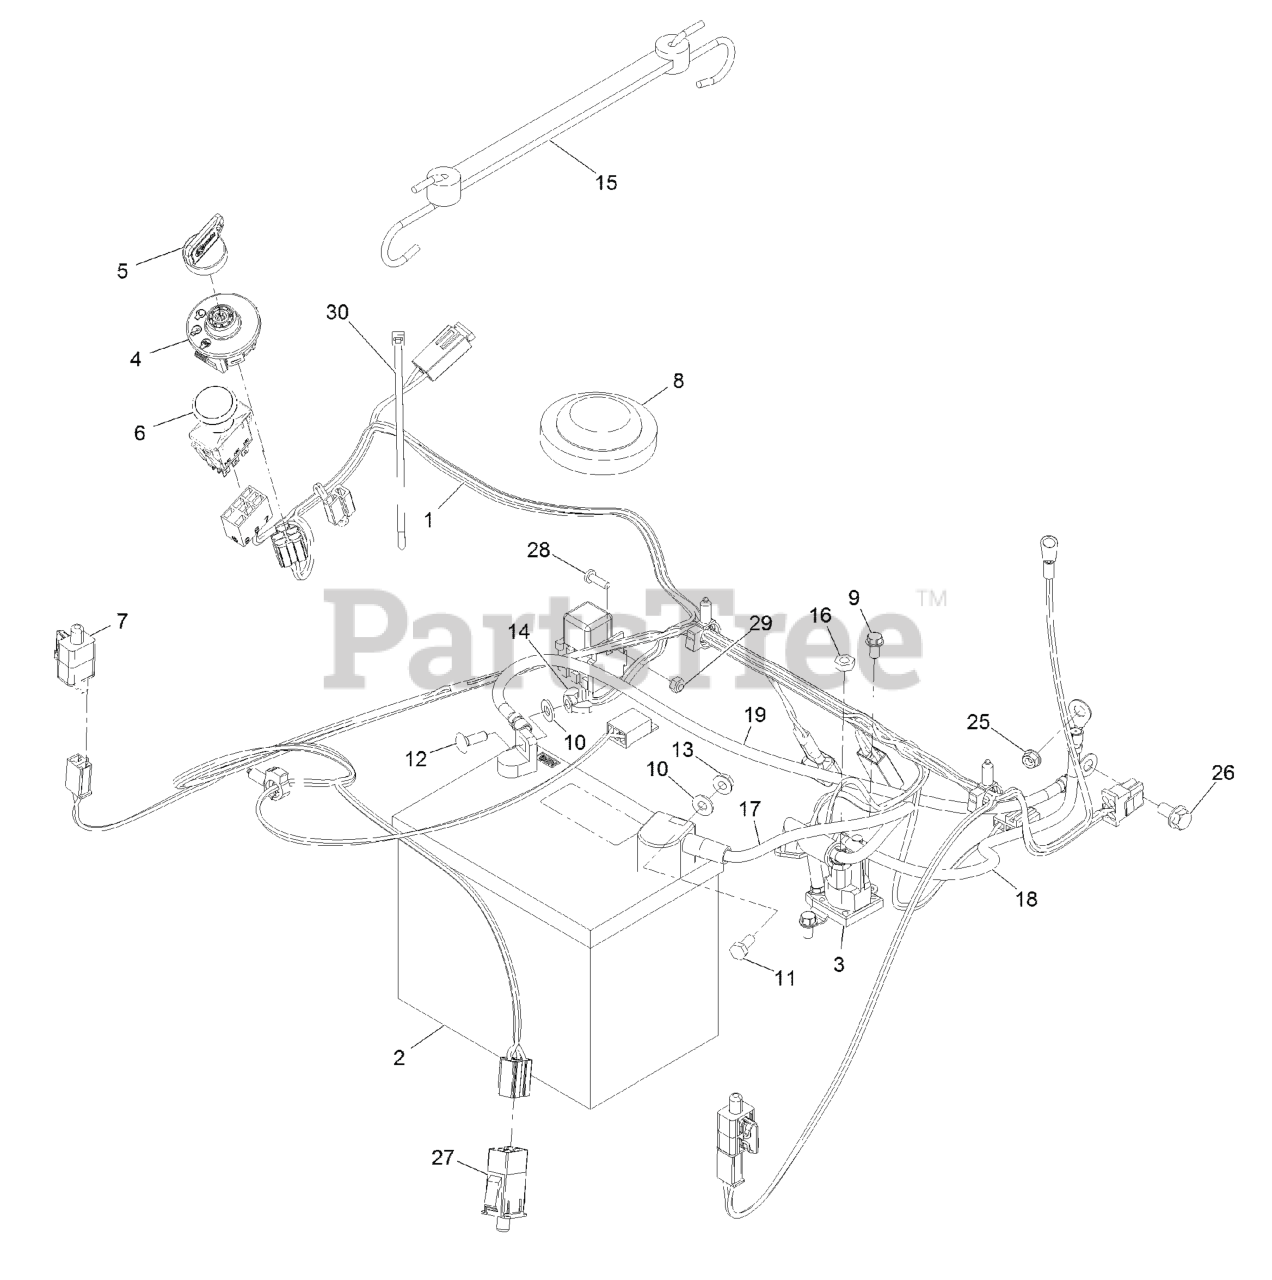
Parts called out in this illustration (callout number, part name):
1	HARNESS-WIRE
2	BATTERY
3	SOLENOID
4	SWITCH-IGNITION
5	KEY-IGNITION
6	SWITCH-PTO
8	SWITCH-SEAT
9	SCREW-HWH
10	WASHER-FLAT
11	SCREW-HH
12	BOLT-CARR
14	NUT-WING
15	HOLDDOWN-BATTERY
16	NUT-JAM
17	CABLE-BATTERY, RED
18	CABLE-BATTERY, POSITIVE
19	CABLE-BATTERY, BLACK
26	SCREW-HHF
27	SWITCH-DELTA
28	SCREW-PPH
29	NUT-LOCK, NI
30	TIE-CABLE
